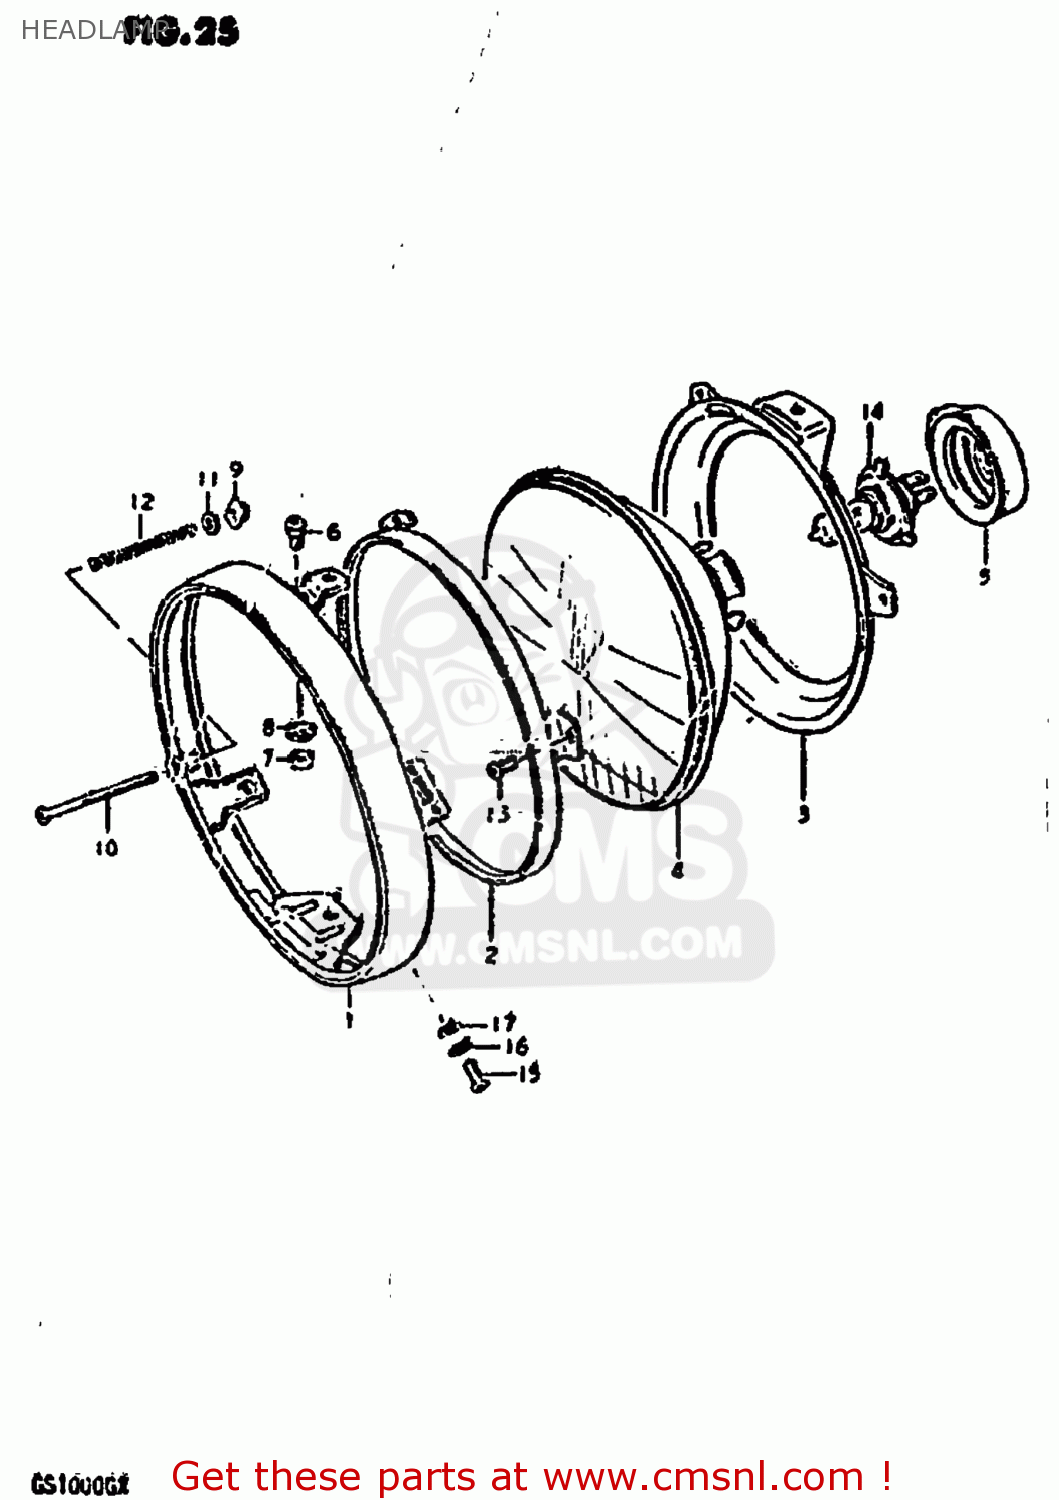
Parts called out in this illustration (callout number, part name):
1	RIM
2	RETAINER
3	RING,HEADLAMP UNIT
4	LAMP UNIT
5	COVER,HEADLAMP SOCKET
6	SCREW
7	NUT,ADJUSTING
8	SPACER
9	NUT
10	SCREW,HEADLAMP ADJUST
11	WASHER
12	SPRING,HEADLAMP ADJUST
13	SCREW
14	BULB(12V60/55W,H4)
15	SCREW
16	WASHER,LOCK
17	WASHER
